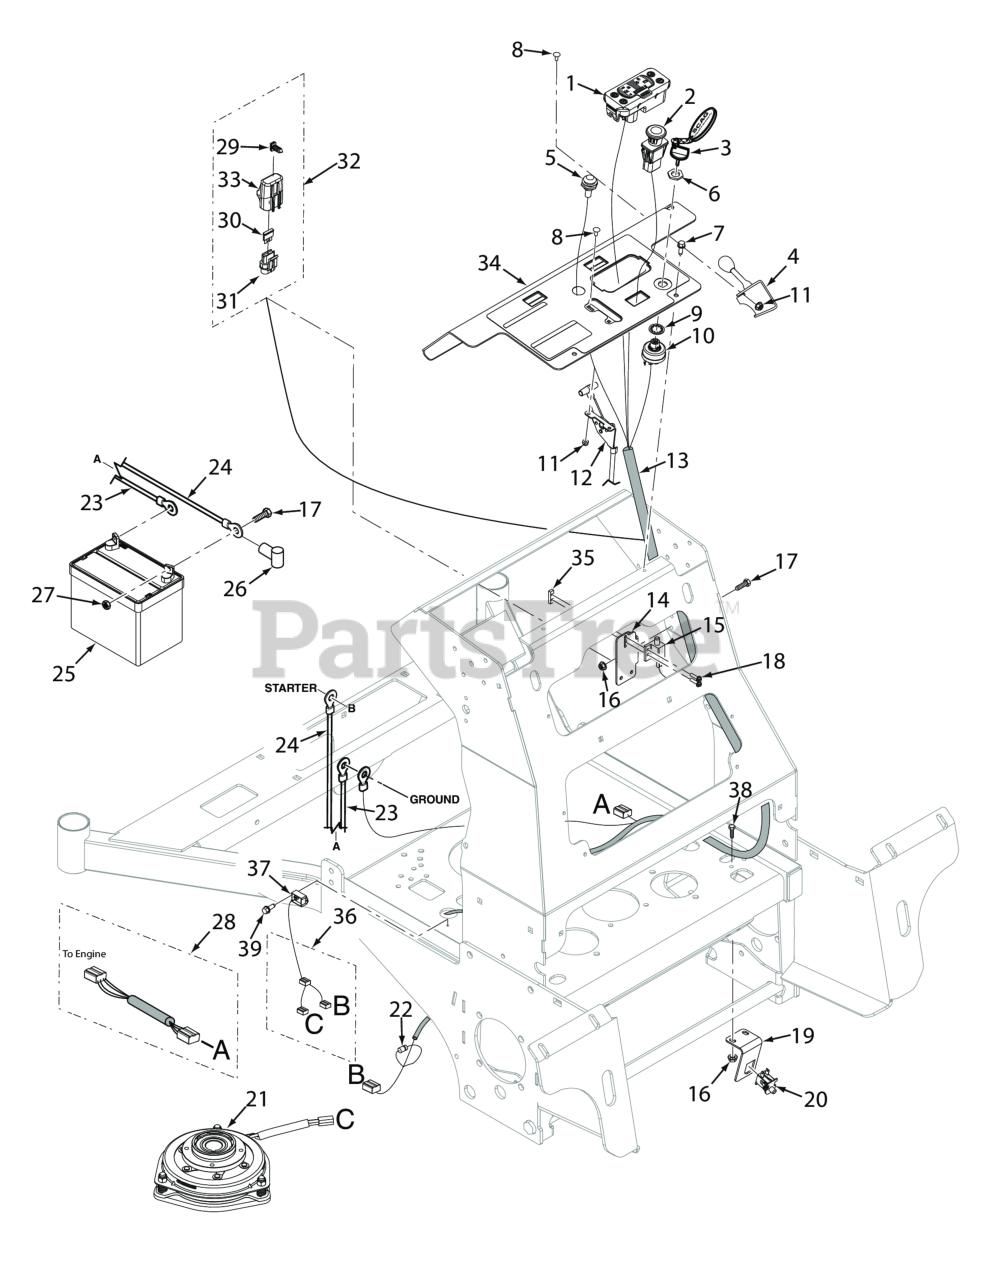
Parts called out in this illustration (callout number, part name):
1	Tiger Eye, Cluster Gauge
2	Switch, PTO - 10 Amp
3	Key, Assembly w/Fob
4	Control Cable, Air Direction
5	Indicator Light, Glow Plugs (Includes Mounting Hardware)
6	Nut, 5/8-32 Special
7	Screw, Self-Tapping 1/4-20 x 3/4
8	Bolt, Carriage #10-24 x 1/2"
9	LOCK WASHER, 5/8" INTERNAL TOOTH
10	KEY SWITCH(INCLUDES MOUNTING HARDWARE)
11	Nut, Elastic Stop #10-24
12	Throttle Control, SVR
13	Wire Harness, SVRII-EFI
14	Bracket, Neutral Switch
15	Switch, Interlock, Park Brake Normally Open
16	NUT, 1/4-20 SERRATED FLANGE HEX HEAD
17	BOLT, HEX HEAD, 1/4-20 X 3/4 GR.5
18	Screw, Hex-Slotted Washer Head #10 32 x 3/4"
19	Switch Bracket, Operator Presence
20	SWITCH, NEUTRAL INTERLOCK
21	Clutch, GT3.5 (28.6mm Bore)
22	Diode, 600V 6 Amp
23	Battery Cable, 39" Black (26EFI) - Kohler
24	Battery Cable, 44" Red w/Braid (26EFI) - Kohler
25	Battery, 350 CCA (not available through Scag)
26	RUBBER BOOT
27	Nut, 1/4 - 20 Hex
28	Wire Harness Adapter, Briggs & Stratton 37 BV-EFI
29	Clip, Fuse Holder
30	FUSE, 20 AMP BLADE TYPE AUTOMOTIVE
31	Fuse Holder Assembly
32	Single Fuse Assy., Excluding Fuse
33	Cover, Sealed Single
34	Control Panel w/Decals
35	Plate, Threaded
36	Wire Harness, Clutch Soft Start
37	Soft Start Module, Clutch
38	Serr. Fl. Hex Head CPSCR, 1/4-20 x 3/4"
39	Screw, #10-32 x .563 Shakeproof
